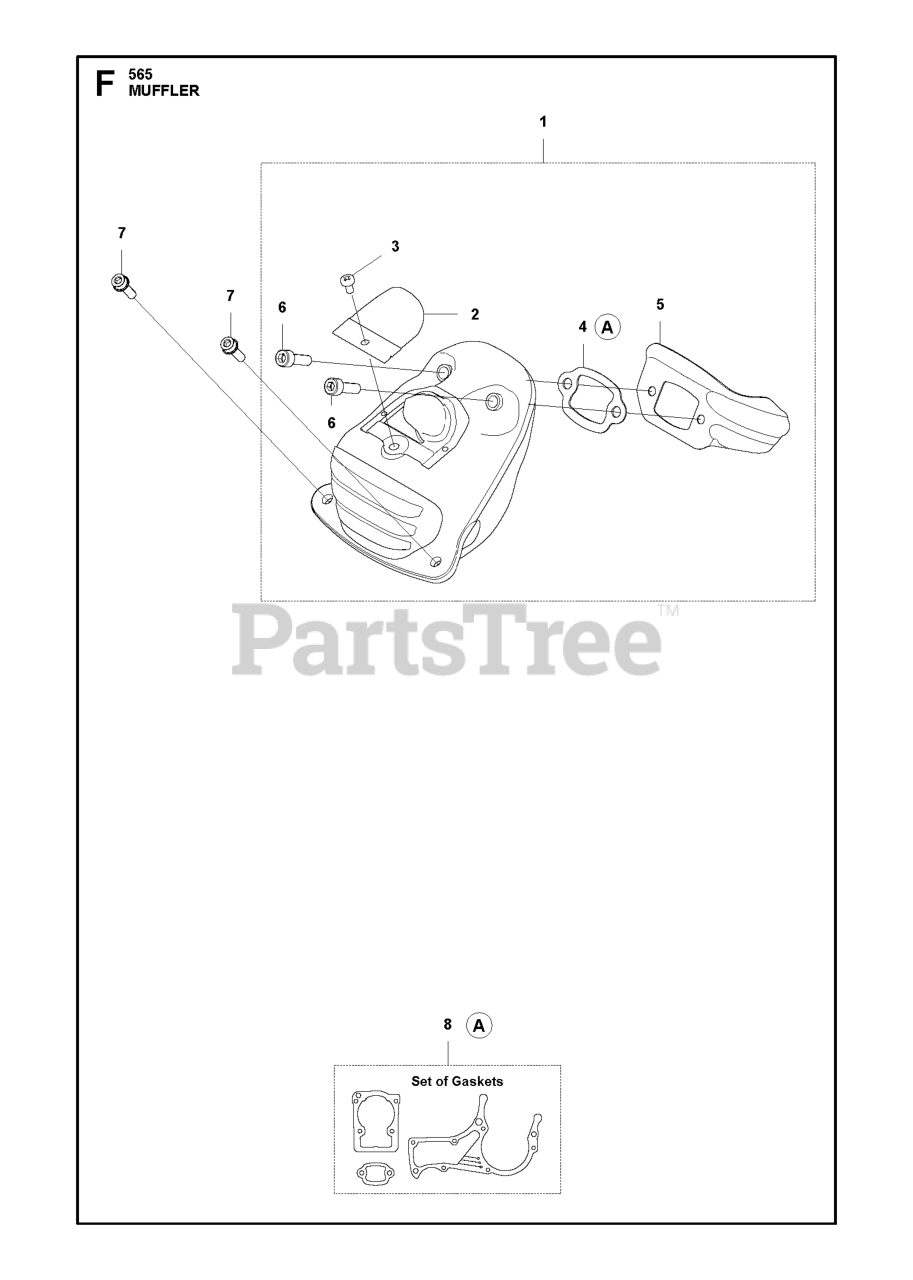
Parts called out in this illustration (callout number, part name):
1	MUFFLER KIT
2	SPARK ARRESTER
4	GASKET MUFFLER A054
5	HEAT DEFLECTOR MUFFLER A054
6	SCREW ITXSCM M6X50 T27 12.9 T
7	SCREW ITXSCM M6X30 T27 10.9 Z
8	GASKET KIT H565/H572
